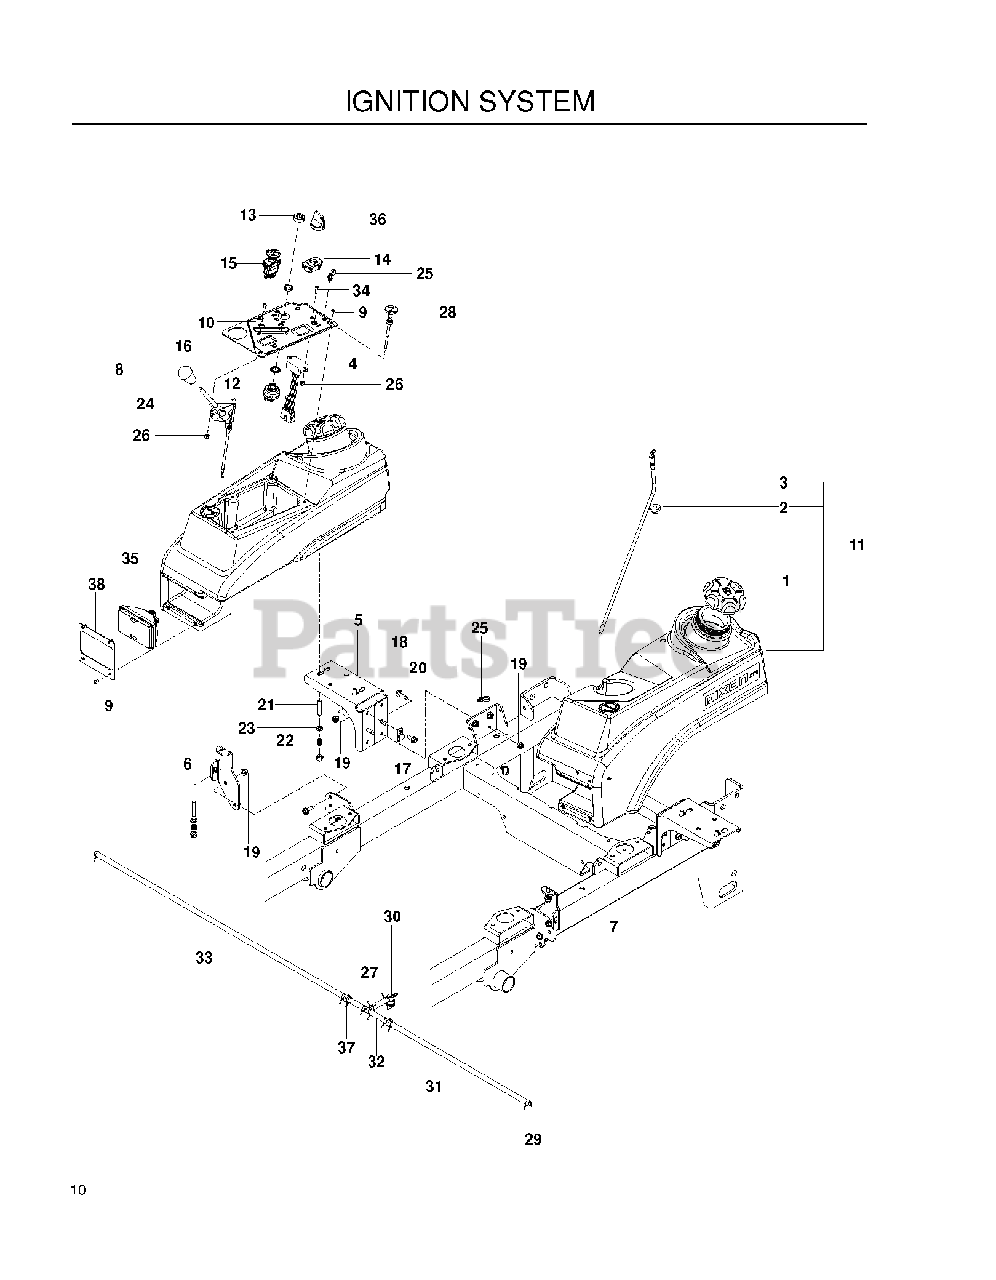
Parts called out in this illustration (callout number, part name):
1	FUEL CAP, GENERIC
2	RUBBER GROMMET
3	FITTING, FUEL, LT
3	FITTING, FUEL, RT
4	TIMER, SEAT
5	MOUNT, TANK RR, BLK
6	MOUNT, TANK, RT, BLK
7	MOUNT, TANK, LT, BLK
8	KNOB - SHIFT
9	SCR #10-24 X 3/8 SKT HD BLK OX
10	Control Decal, YK
11	FUEL TANK ASSY, LT
11	ASSEMBLY, RT TANK, DIXON
12	SWITCH, IGNITION, INDAK
13	CAP IGNITION NUT
14	HOUR METER
15	SWITCH, PTO 10 AMP
16	PLATE, CONTROL, BLK
17	DOUBLE TUBE CLAMP
18	Hex Washer Head Bolt, 5/16-18 X 3/4 Thread Forming
19	5/16-18 NYLOC FLANGE NUT
20	HHFS 5/16-18 X 3/4
21	STUD, 5/16C
23	FLAT WASHER 5/16 SAE
24	CABLE, THROTTLE, 46"
25	TIE WRAP, 8-3/8", W/CLIP
26	NUT 10-24 NYLOC
27	TEE, FUEL LINE, .25
28	Choke Cable, 48"
29	HOSE CLAMP
30	FUEL VALVE
31	FUEL LINE
32	FUEL LINE 2.5"
33	HOSE 35"
34	SCR #10-24 X .75 SKT HD BLK
36	KEY, IGNITION
37	VALVE, CHECK, .25
38	PLATE LIGHT
